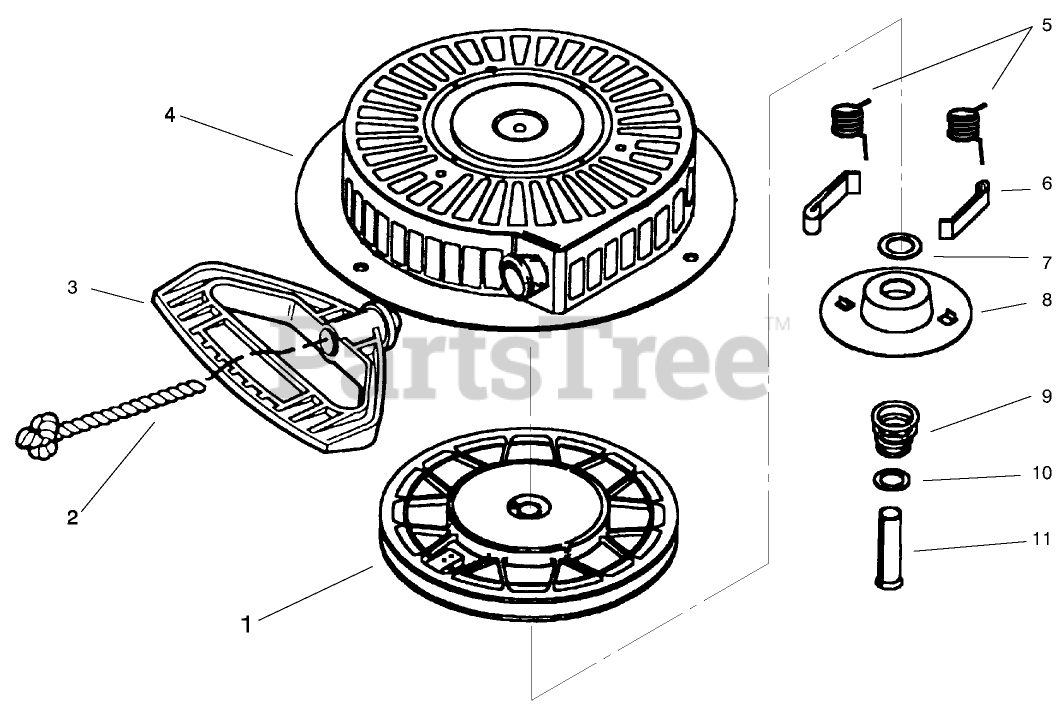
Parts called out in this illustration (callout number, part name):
1	Pulley and Rewind Spring ASM
2	Rope-Starter (98 cut to length)
3	Handle-Starter, Mitten Grip
4	Starter Housing ASM
5	Spring-Dog
6	Dog-Starter
7	Washer
8	Retainer
9	Spring-Brake
10	Washer
11	Pin, Spring (Incl. Ref. #7)
